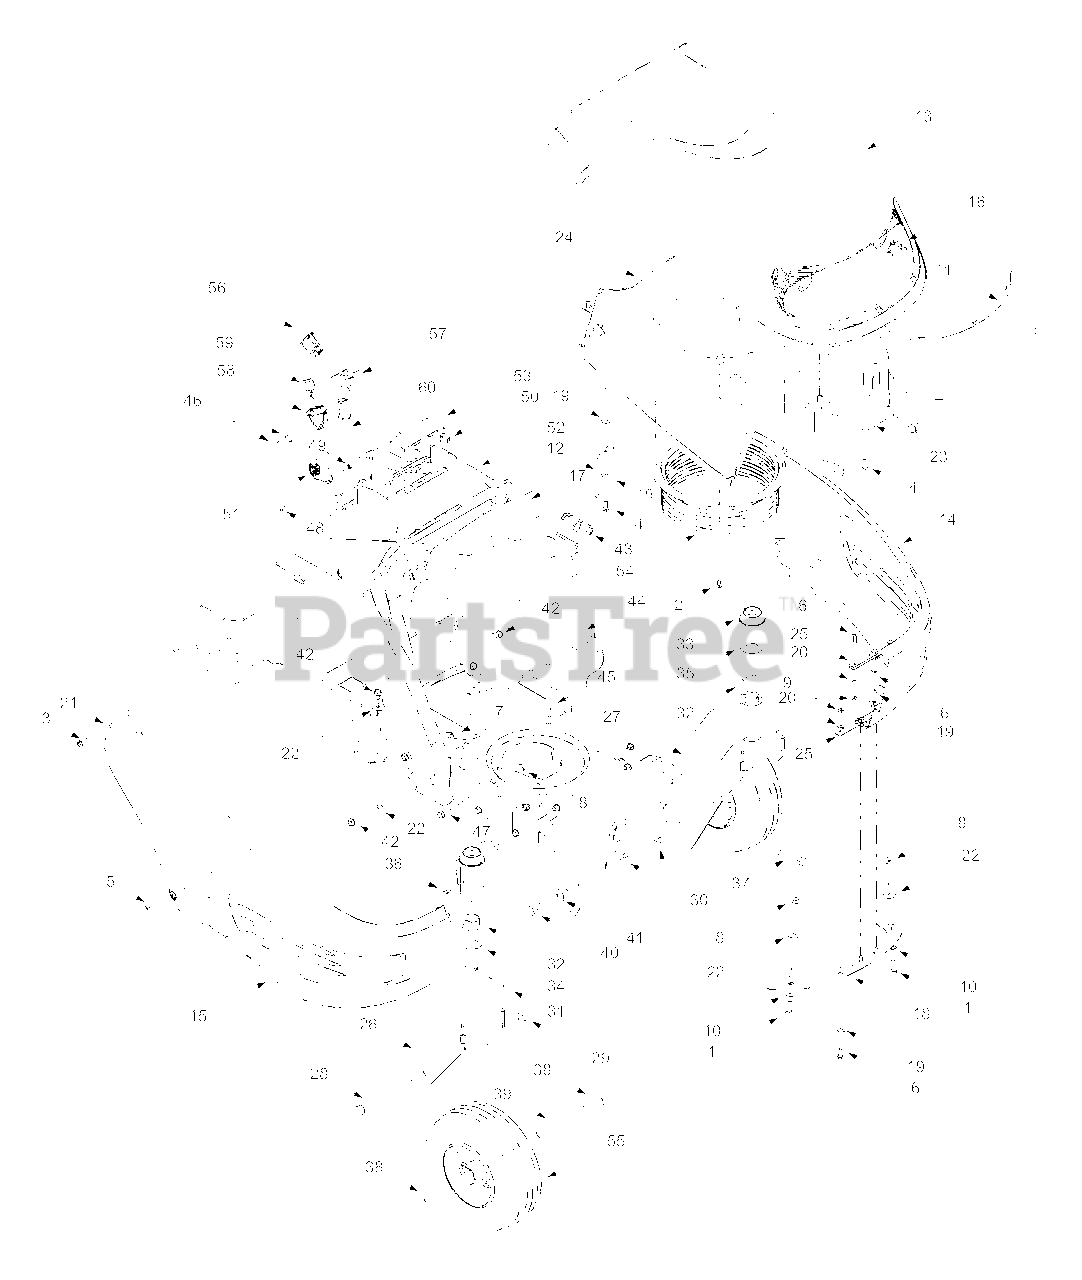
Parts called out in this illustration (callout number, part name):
1	Hex Cap Screw, 5/16-18 x 1.0
2	Self-tapping Screw, 1/4-20 x .5
3	Self-tapping Screw, 1/4-20 x .75
4	Self-tapping Screw, 1/4-15 x .75
5	Pan Phillips Screw, 1/4-20 x .75
6	Hex Cap Screw, 1/4-20 x .75
7	U-type Speed Nut, 1/4-20
8	Flange Lock Nut, 5/16-18
9	Hex Nut, 1/4-20
11	Head Light Lens
12	Hood Latch Rod
13	Hood, 6-style (Gray)
14	LH Side Panel, 6-style (Gray)
15	RH Side Panel, 6-style (Gray)
16	Head Light Assembly
19	Flat Washer, .28 x .74 x .063
20	Lock Washer, 1/4
21	Flat Washer, .283 x .75 x .030
22	Flat Washer, .349 x 1.0 x .063
29	Hex Lock Nut, 1/2-20
30	Flange Lock Nut, 3/8-16
31	Cotter Pin, .125 x 1.5
32	Flange Bearing
34	Flat Washer, 1.031 x 1.620 x .095
35	Flat Washer, 1.010 x 2.0 x .065
36	Grease Fitting, 1/4-28
37	Shoulder Screw, .50 x 2.23, 3/8-16
38	Spacer, .790 x .347
40	Shoulder Screw, 3/8-16
41	Bell Washer, .39 x 1.13 x .062
42	Self-tapping Screw, 16-18 x .625
43	Fuel Tank Cap (fits both fuel tanks)
44	Fuel Tank, Two-gallon (shown)
47	Hex Head Washer Screw, 5/16-18 x .875
48	Torx Screw, #8-32 x .375
49	Hex Nut, 8-32
50	Cap Plug, .812
51	Throttle Control Lever
54	Intake Bellow (ZTT-1850)
55	Wheel Assembly, 11 x 4 x 5 (Yellow Rim)
56	Electric PTO Switch
57	Systems Indicator Monitor/Hour Meter
58	Ignition Switch
59	Ignition Key w/ Plastic Cover
60	Choke Control/Cable (ZTT-2150)
